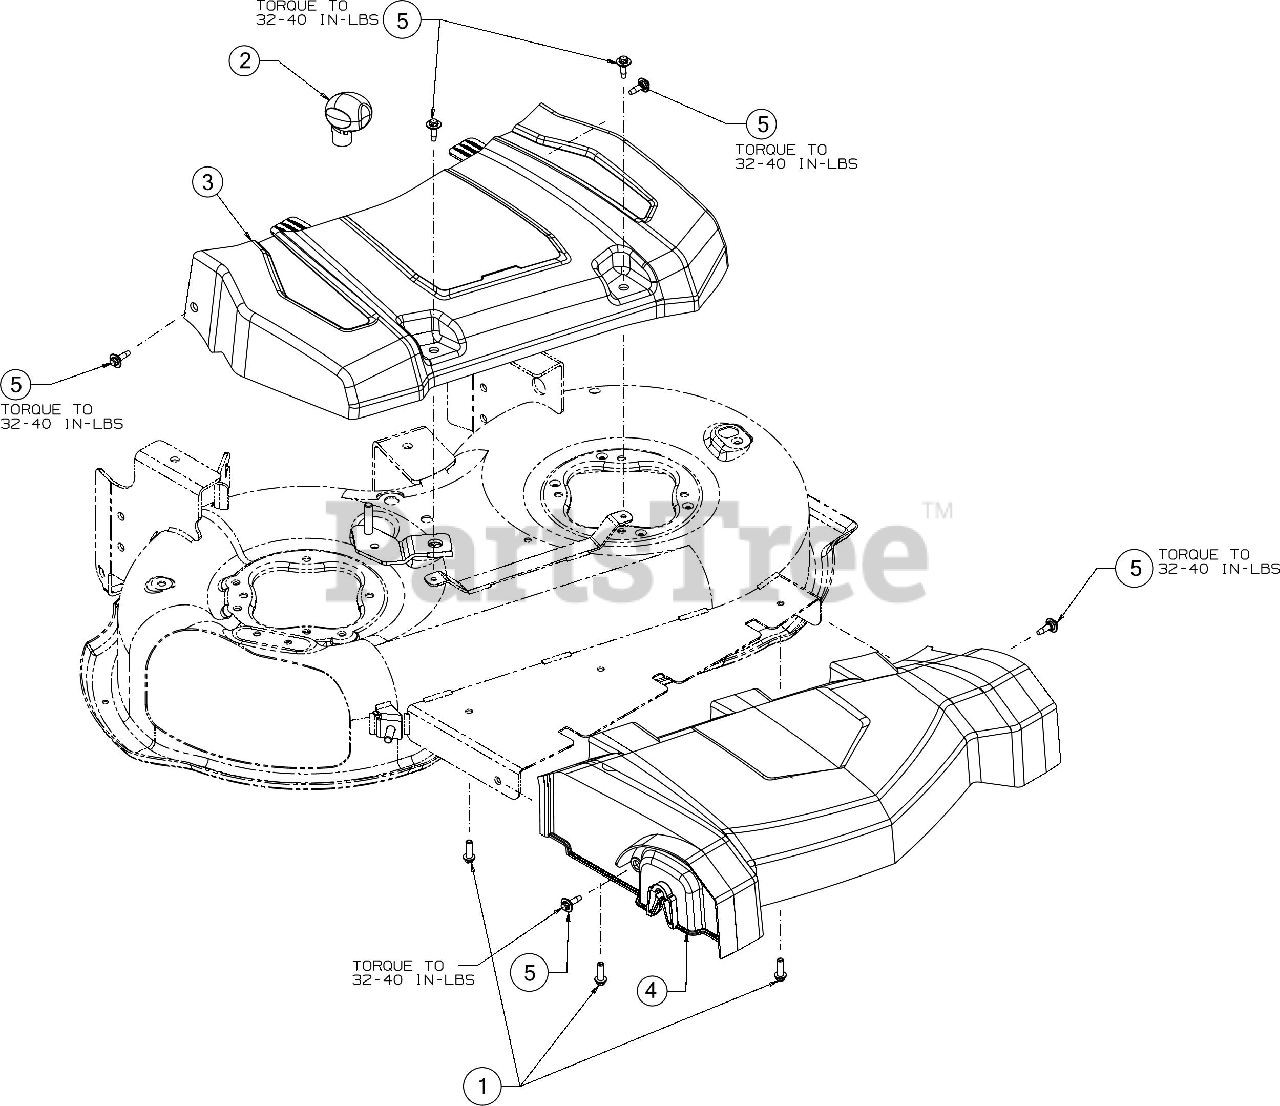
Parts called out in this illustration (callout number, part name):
1	SCREW 1/4 x .750
2	HEIGHT ADJUSTMENT KNOB-BLACK
3	28" BELT COVER
4	FRONT AXLE COVER
5	SHOULDER SCREW M6-1 .368 X.115
